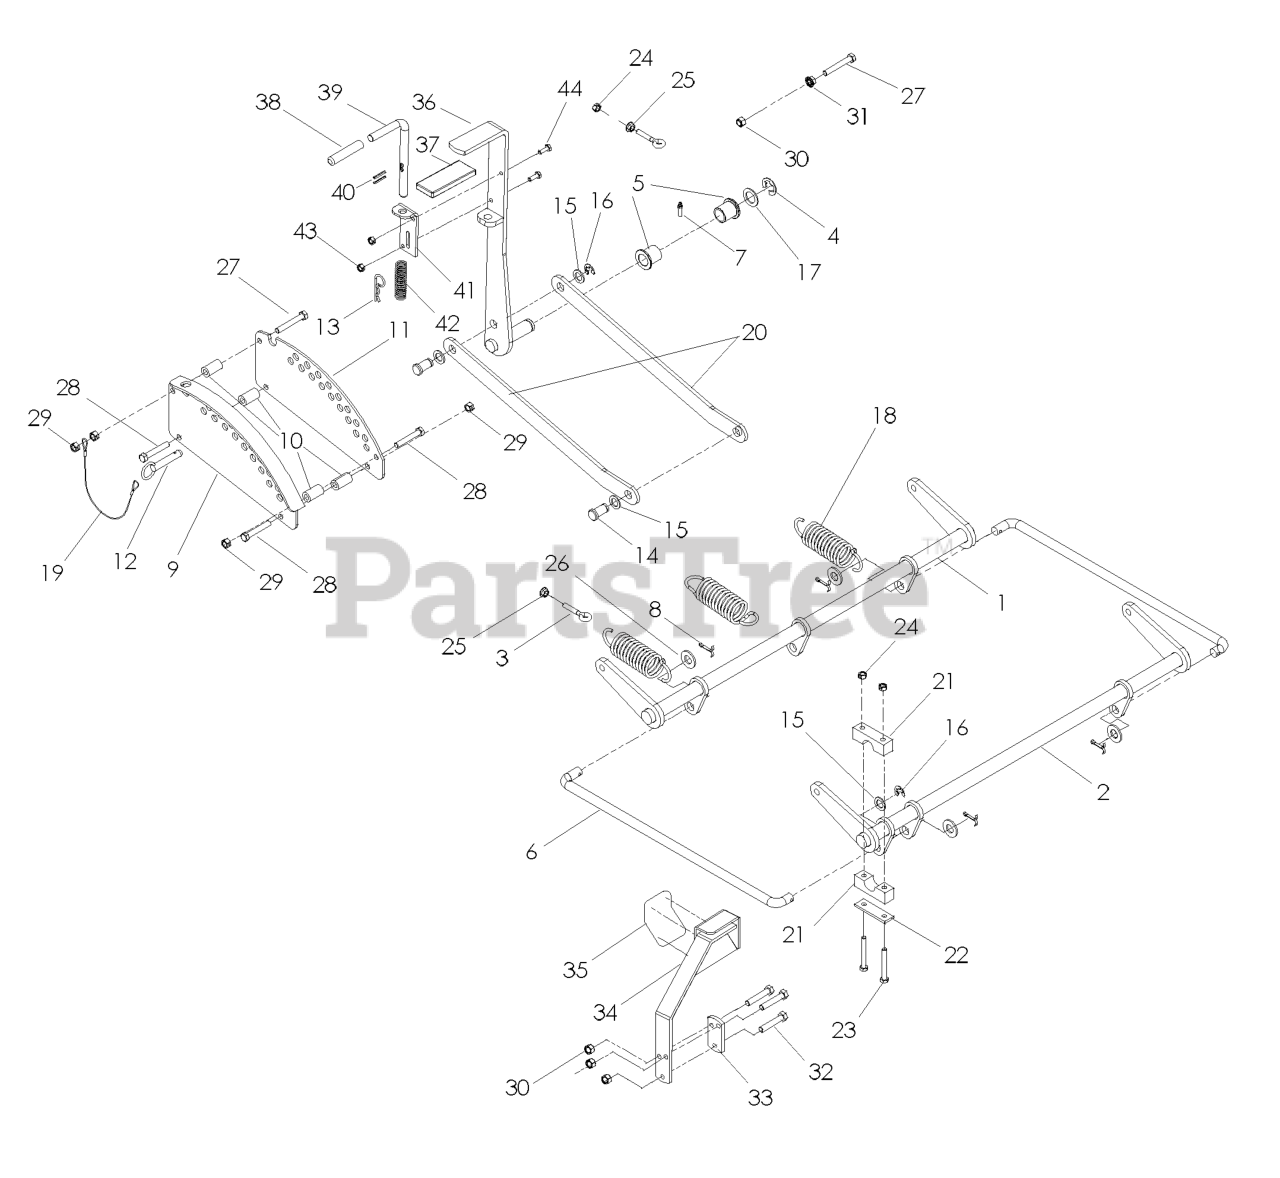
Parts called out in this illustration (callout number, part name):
1	SHAFT LIFT REAR
2	LIFT SHAFT
3	EYEBOLT, RH
4	E-RING 7/8
5	BUSHING, FLANGED
6	CONNECTING LINK
7	GREASE ZERK LONG
8	COTTER PIN
9	ADJ. PLATE WLDMNT
10	DECK LIFT SPACER
11	ADJ. PLATE PAINTED
13	HAIRPIN #4
14	CLEVIS PIN
15	BUSHING
16	E-RING 5/8
17	BSHG .875 X 1.375 X .074 ZD
18	DECK LIFT SPRING
20	LIFT LINKAGE,PAINTED
21	PILLOW BLOCK
22	REINFORCEMENT BAR
23	BOLT 5/16C X 2 1/2
24	NUT 5/16C CENTERLOCK
25	NUT 5/16C WHIZ
26	WASHER 5/8 FLAT
27	HCS 3/8C X 2 1/2
28	HCS 3/8C X 2 1/4
29	NUT 3/8C CENTERBLOCK
30	NUT 3/8-16 NYLOC
31	NUT 3/8C WHIZ
32	HCS 3/8C X 1 1/2
33	TIGHTENING PLATE BLK
34	LIFT PEDAL BLK
35	ANTI-SKID PAD
36	LIFT LEVER WELDMENT
41	PIN MT, UPPER
43	NUT 1/4C CENTER LOCK
44	HCS 1/4C X 3/4 HCS
